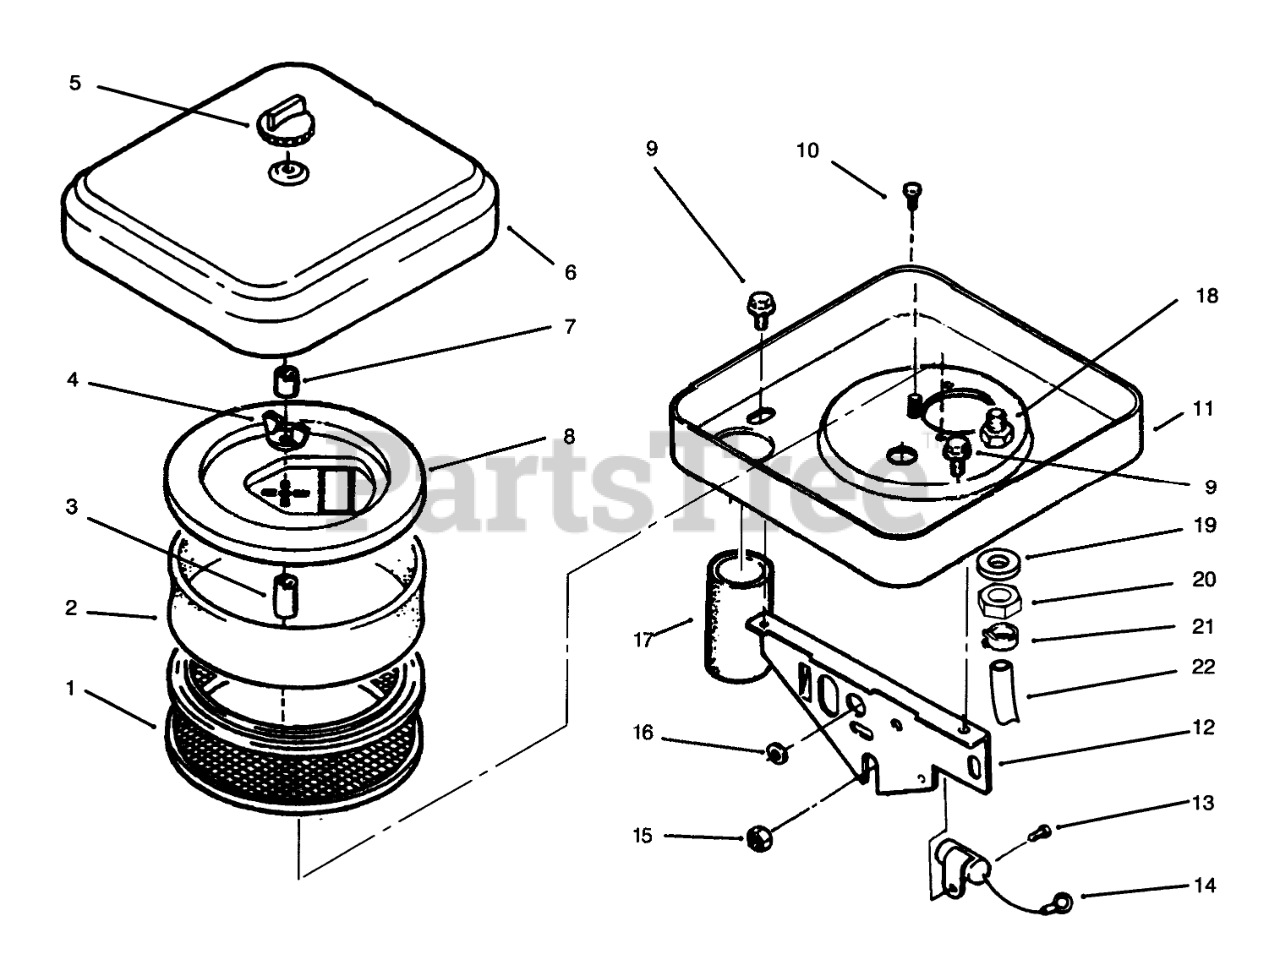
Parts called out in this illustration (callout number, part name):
1	AIR-CLEANER ELEMENT
2	AIR CLEANER ELEMENT
3	SPACER-1" LG
4	1/4-20 WING NUT
6	CHROME-AIR CLEANER
7	SPACER-RUBBER
8	ELEMENT COVER KIT
9	SCREW-TAPPING
10	MACHINE SCREW
11	AIR-CLEANER HOUSING
12	SUPPORT-AIR CLEANER
13	SCREW #10-32 X 5/8
14	CONDENSER
15	WASHER-LOCK
16	GROMMET
17	AIR INTAKE TUBE
18	Fitting-Barbed
19	HOSE FITTING GASKET
20	TAPPET NUT
21	CLAMP-HOSE
